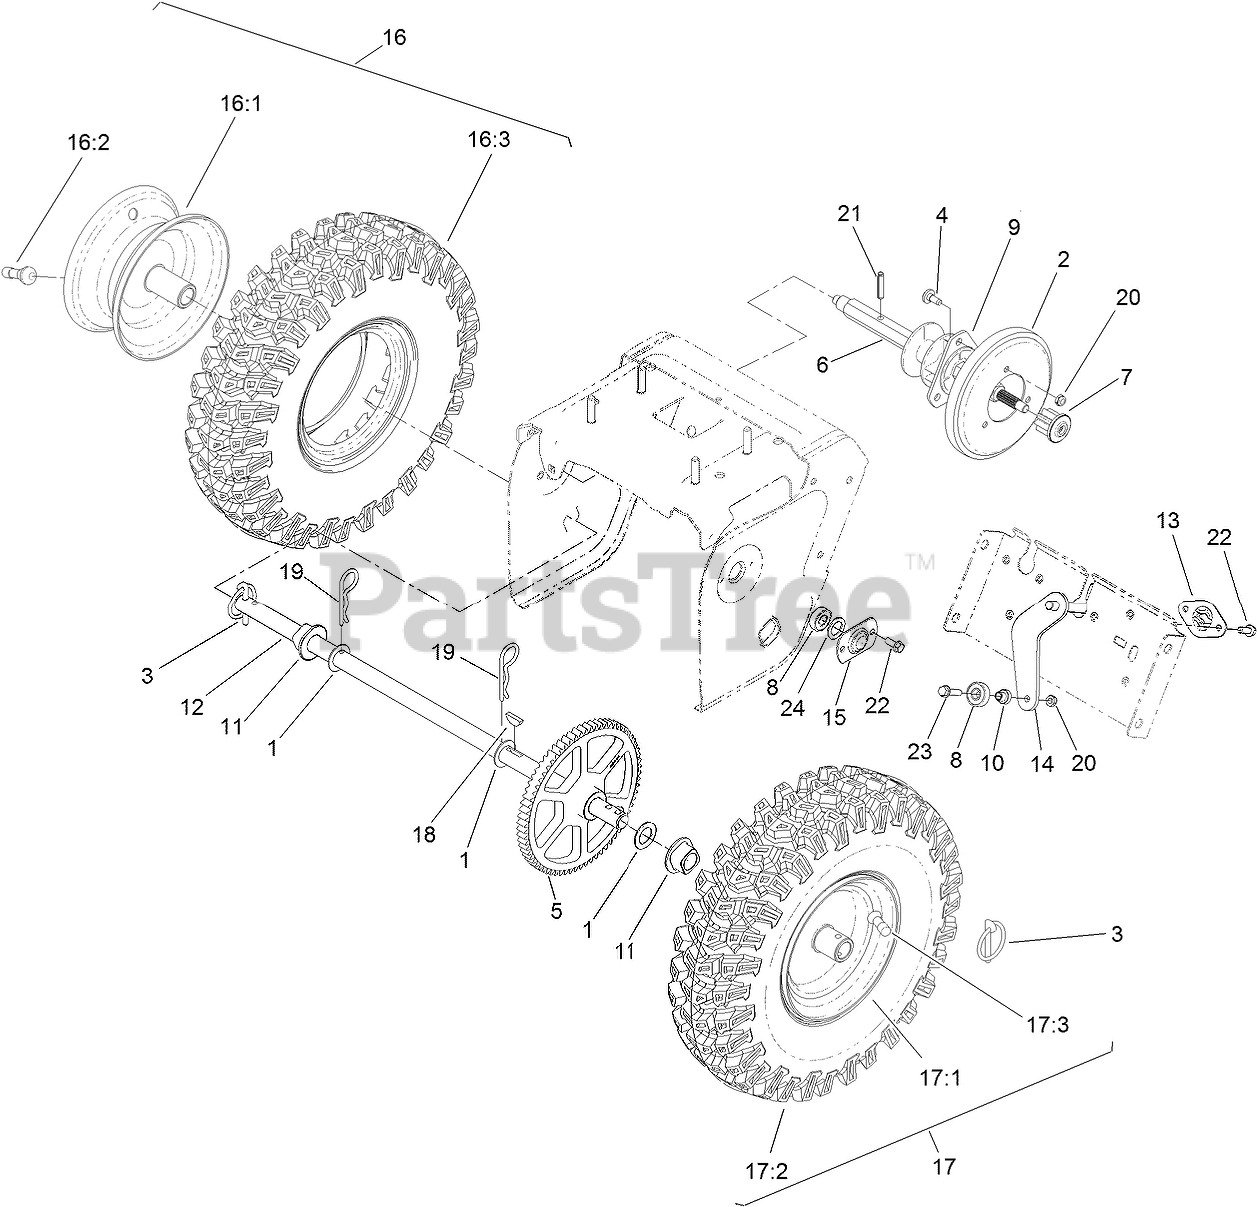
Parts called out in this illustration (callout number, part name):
1	WASHER-THRUST
2	WHEEL-FRICTION
3	KLIK PIN ASM
4	SCREW-SHOULDER
5	GEAR-AXLE
6	SHAFT-HEX
7	GEAR-PINION, 8 TOOTH
8	BEARING-BALL
9	TRUNNION
10	SPACER-PLATE, SHIFT
11	BUSHING-AXLE
13	RETAINER-PLATE, SHIFT
14	SHIFT PLATE ASM
15	RETAINER-BEARING
16	LH WHEEL AND TIRE ASM
16:1	WHEEL (15X4 TIRE)
17	RH WHEEL AND TIRE ASM
17:1	WHEEL (15X4 TIRE)
18	KEY-WOODRUFF
19	PIN-HAIR
20	NUT-LOCK, NI
21	PIN-ROLL, SLOTTED
22	SCREW-HWH
23	SCREW-HWHTF
24	WASHER-RUBBER
